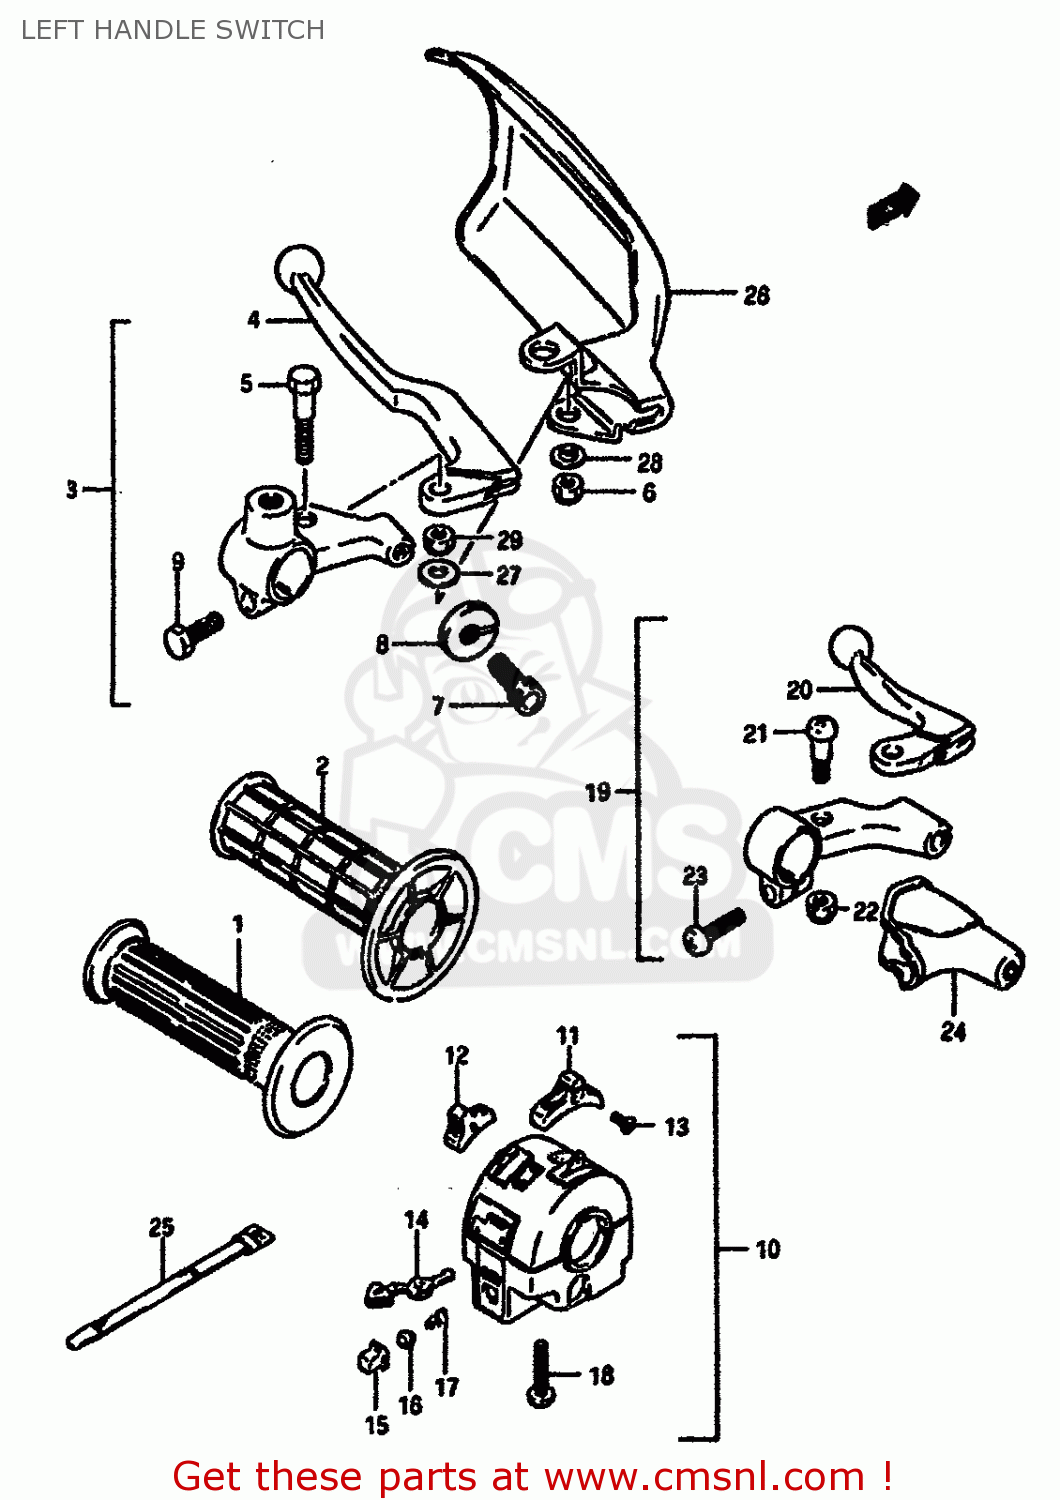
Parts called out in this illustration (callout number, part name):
1	GRIP,L
2	GRIP,LEFT
3	LEVER ASSY,CLUTCH
4	LEVER,CLUTCH
5	BOLT,LEVER SET
6	NUT
7	ADJUSTER,CABLE
8	NUT,CABLE ADJUSTER LOCK
9	BOLT
10	SWITCH ASSY,HANDLE,LH
11	KNOB,LIGHTING SWITCH
12	KNOB,DIMMER SWITCH
13	SCREW
14	KNOB,TURNSIGNAL
15	BUTTON,HORN
16	CONTACT
17	SPRING
18	SCREW
19	LEVER ASSEMBLY,DECOMPRESSION
20	LEVER,DECOMP
21	BOLT,LEVER
22	NUT
23	SCREW
24	COVER,DECOMP LEVER DUST
25	CLAMP(L:120)
26	COVER,KNUCKLE,L
27	WASHER(6.5X16X1.2)
28	WASHER
29	NUT 6MM
